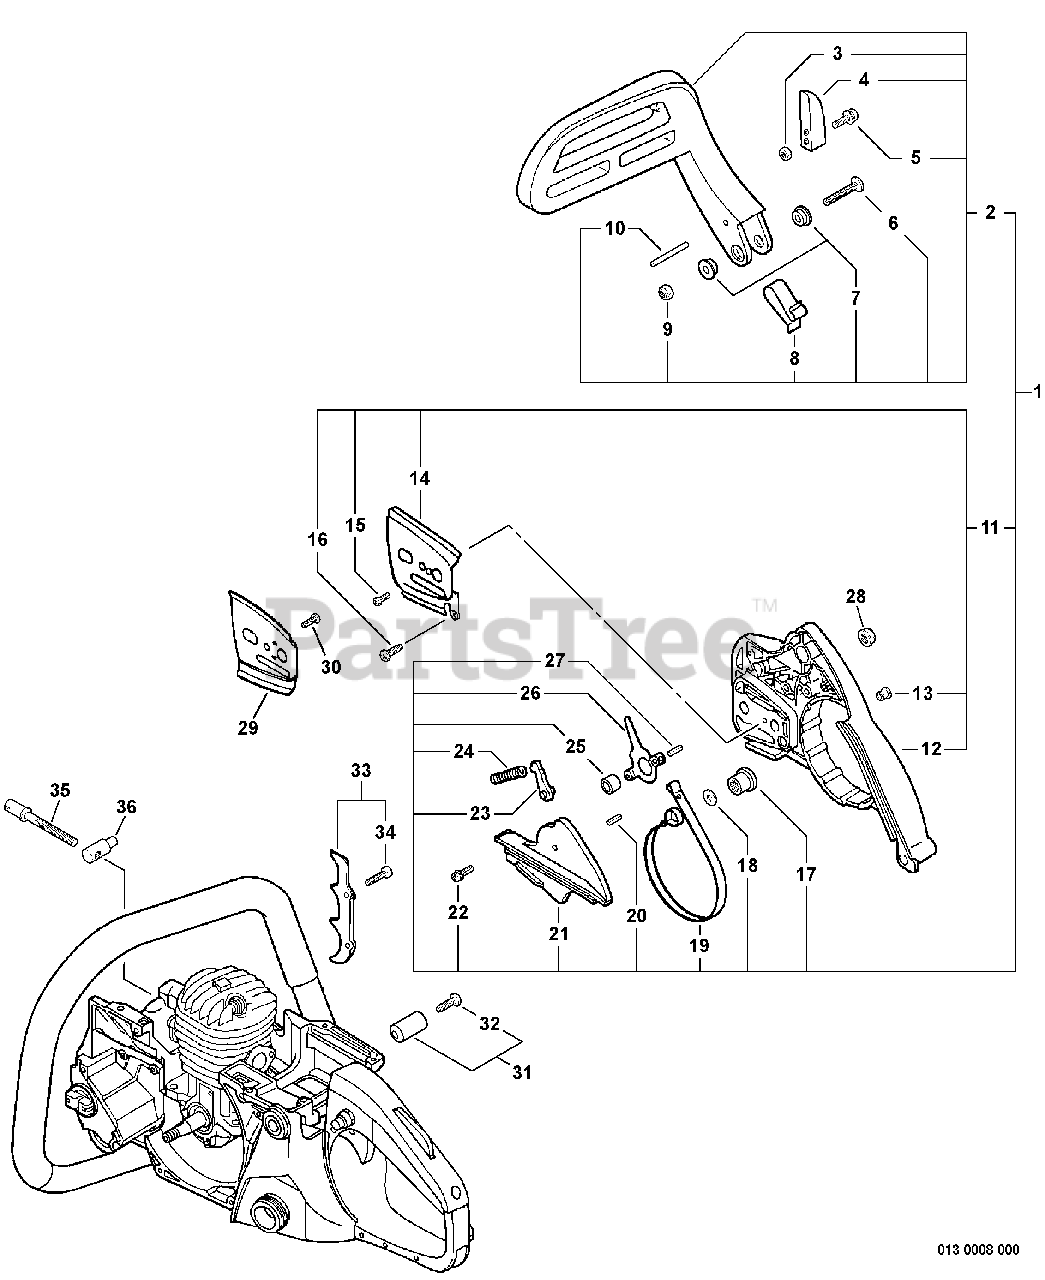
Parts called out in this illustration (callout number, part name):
1	CHAIN BRAKE ASSY
2	BRAKE LEVER ASSY
4	WEIGHT, BRAKE
5	SCREW 4×18
6	SCREW 5×32
7	COLLAR 5.3×10×13×L5
8	SPRING, FLAT
9	NUT, LOCK M5
10	PIN 3×24
11	SPROCKET GUARD ASSY
12	GUARD, SPROCKET
14	PLATE, GUIDE - OUTER
15	SCREW 3×6
16	SCREW 4×10
17	ADJUSTER, BRAKE
18	WASHER 8
19	BAND, BRAKE
20	PIN, SPRING 2.5×12
21	COVER, BRAKE
22	SCREW 4×10
23	STOPPER, BRAKE
24	SPRING, COMPRESSION
25	WASHER 5.2×12×14
26	LEVER, BRAKE
27	PIN, SPRING 4×8.8
28	NUT, FLANGE M8×1.25
29	PLATE, GUIDE - INNER
30	SCREW 4×6
31	CHAIN CATCHER KIT
32	SCREW 5×18
33	SPIKE KIT, BUMPER
34	BOLT 5×12
35	SCREW, CHAIN TENSION
36	TENSIONER, CHAIN
